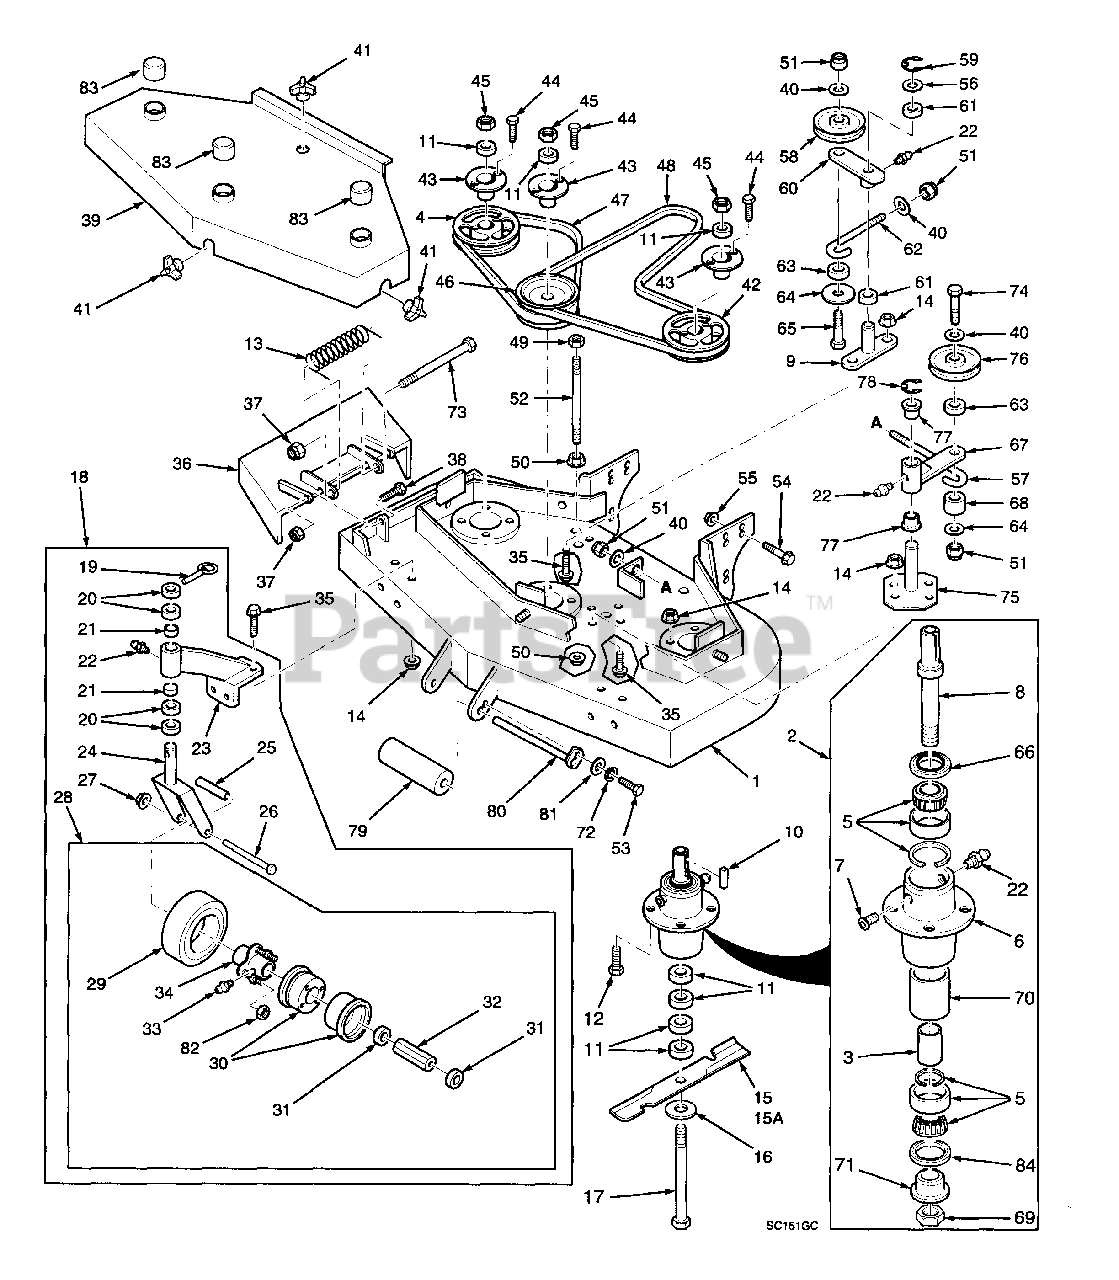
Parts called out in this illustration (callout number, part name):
1	Cutter Deck
2	Spindle Assembly
3	Sleeve, Cutter Spindle
4	Pulley
5	Tapered Bearing
6	Spindle Housing
7	Relief Fitting, Cutter Spindle
8	Spindle Shaft
9	Idler Pivot
10	Key, 1/4 x 1/4 x 2"
11	Spacer, Cutter Blade
12	Hex Head Bolt, 5/16-18 x 1-1/4"
13	Spring, Chute Return
14	Nut, 5/16-18 Serr. Flange
15	Cutter Blade 16-1/2"
15A	Cutter Blade 16-1/2" High Lift
16	Flat Washer, (.688 x 1.75 x .134)
17	Hex Head Bolt, 5/8-11 x 9-1/2"
18	Caster Assy.
19	Quick Pin
20	Spacer, Caster Yoke, 1/2" Thick
21	Bushing, 5/8 x 1", Flanged
22	Grease Fitting Str. 1/4-28
23	Support Assy.
24	Caster Yoke
25	Sleeve, Caster Wheel Bearing
26	Hex Head Bolt, 1/2-13 x 5-1/2"
27	Nut, 1/2-13 Elastic Stop
28	Wheel Assy.,
29	Tire Only, Caster Wheel
30	Rim Pair, Caster Wheel
31	Bearing Retainer, Caster Wheel
32	Roller Bearing, Caster Wheel
33	Grease Fitting 45 Deg., 1/4-28
34	Hub Assy.,
35	Capscrew, 5/16-18 x 3/4"
36	Discharge Chute
37	Nut, 5/16-18 Elastic Stop
38	Hex Head Bolt, 5/16-18 x 1"
39	Belt Cover,
40	Flat Washer, (.391 x .938 x .105)
41	Wing Nut, 3/8-16
42	Pulley
43	Tapered Hub
44	Hex Head Bolt, 1/4-20 x 3/4"
45	Nut, 5/8-11 Hex Head
46	Pulley, Double
47	Belt, RH Blade Drive
48	Belt, Blade Drive
49	Nut, 3/8-16 Centerlock
50	Nut, 3/8-16 Serr. Flange
51	Nut, 3/8-16 Elastic Stop
52	Support, Belt Cover
53	Hex Head Bolt, 5/16-18 x 3/4"
54	Capscrew, 7/16-14 x 1" Serr.
55	Nut, 7/16-14 Serr. Flange
56	Flat Washer, 3/4 Special
57	J-Hook
58	Idler Pulley, "V" Groove
59	Retaining Ring, 3/4" Ext. "E"
60	Idler Arm Assy.
61	Bushing, 3/4 x 1/2"
62	J-Hook, Idler Pulley
63	Spacer, Pulley
64	Flat Washer, 3/8 x 1-1/2 x 16 Ga.
65	Hex Head Bolt, 3/8-16 x 2-1/4"
66	Seal, Cutter Spindle
67	Idler Arm Assy.
68	Spacer, J-Hook
69	Nut, Cutter Spindle
70	Spacer, Outside
71	Spindle Bushing
72	Lock Washer, 5/16"
73	Hex Head Bolt, 5/16-18 x 4-1/4"
74	Hex Head Bolt, 3/8-16 x 3-1/2"
75	Idler Pivot
76	Idler Pulley, Clutch Belt
77	Bushing, 1-1/8 x 1.0 Flanged
78	Retaining Ring, 1-1/8 Ext. "E"
79	Guide, Roller
80	Roller Shaft
81	Flatwshr., 5/16 (.375 x .875 x .083)
82	Nut, 5/16-24 Tapered
83	Shield, Spindle
84	Seal, Cutter Spindle
